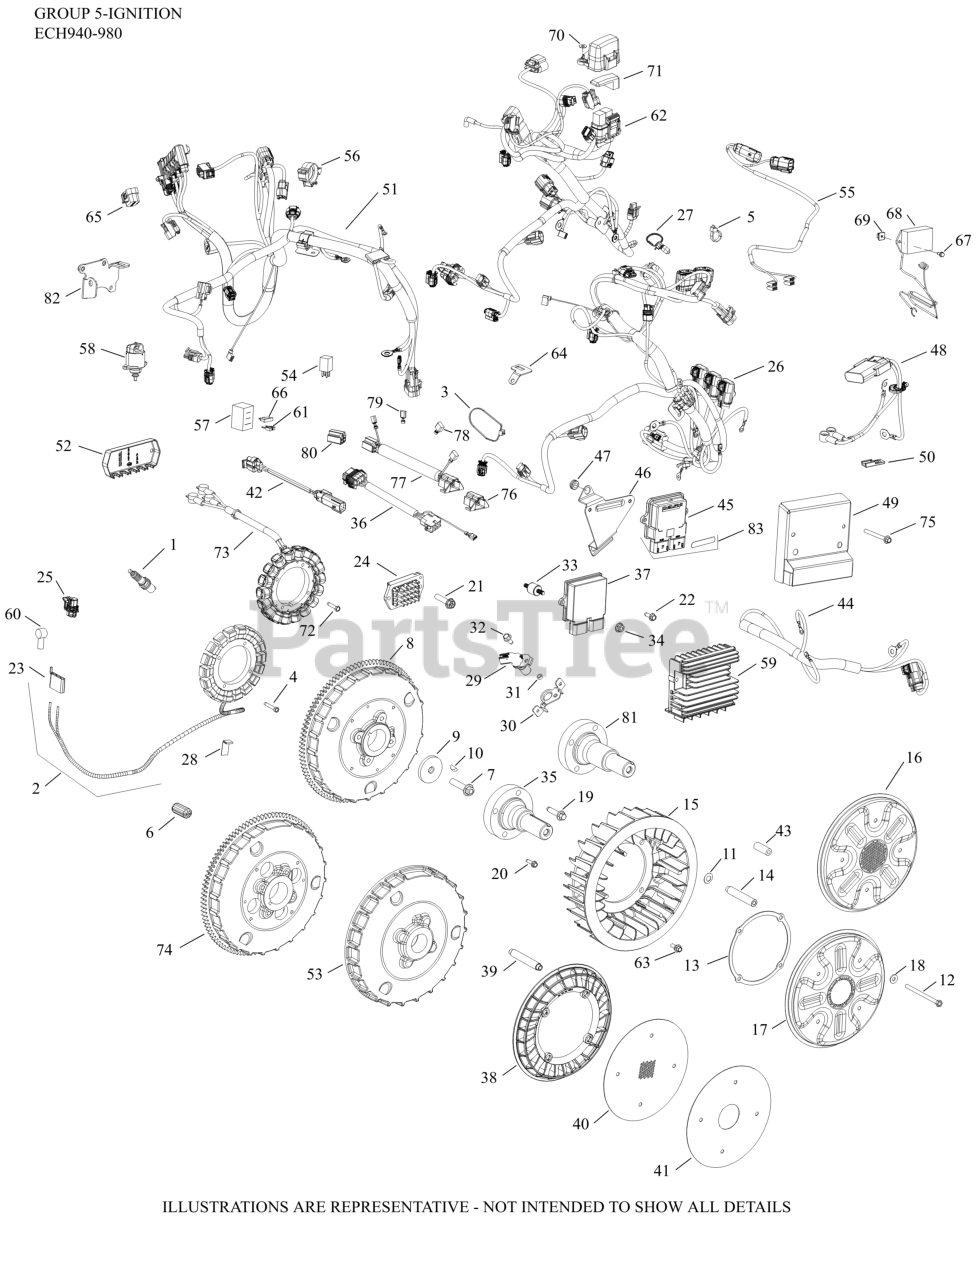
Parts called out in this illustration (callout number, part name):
1	PLUG, SPARK
2	KIT, 25 AMP STATOR ASSY.
3	TIE, CABLE
4	SCREW, THREAD FORMING
5	TIE, WIRE
6	SLEEVE, EMI SUPPRESSION
7	SCREW, FLG M10X1.5X45-USE 25 086 361-S
8	FLYWHEEL ASSEMBLY
9	WASHER, FLAT 13/32"
10	KEY, 3/16" X 5/8"
11	WASHER, SPRING 10 MM
12	SCREW, HEX HEAD
13	RING, SUPPORT
14	SPACER, GRASS SCREEN
15	FAN
16	SCREEN, GRASS
18	WASHER, FLAT 1/4" (O.D. 5/8")
20	SCREW, THREAD FORMING
21	SCREW, HEX FLANGE HI-LO
22	SCREW, THREAD FORMING
23	CONNECTOR
24	REGULATOR, RECT (20-30AMP, FW W/OVP)
26	HARNESS, WIRING ASSEMBLY - EFI
27	TIE, WIRE
28	CLIP, BLOWER HOUSING
29	SENSOR, SPEED
30	BRACKET, CRANK SENSOR
32	SCREW, THREAD FORMING
33	ISOLATOR, VIBRATION STUD
34	NUT, FLG M5X.8
37	MODULE, ECU
NI	CAP, CONNECTOR (4-WAY, BLACK)
